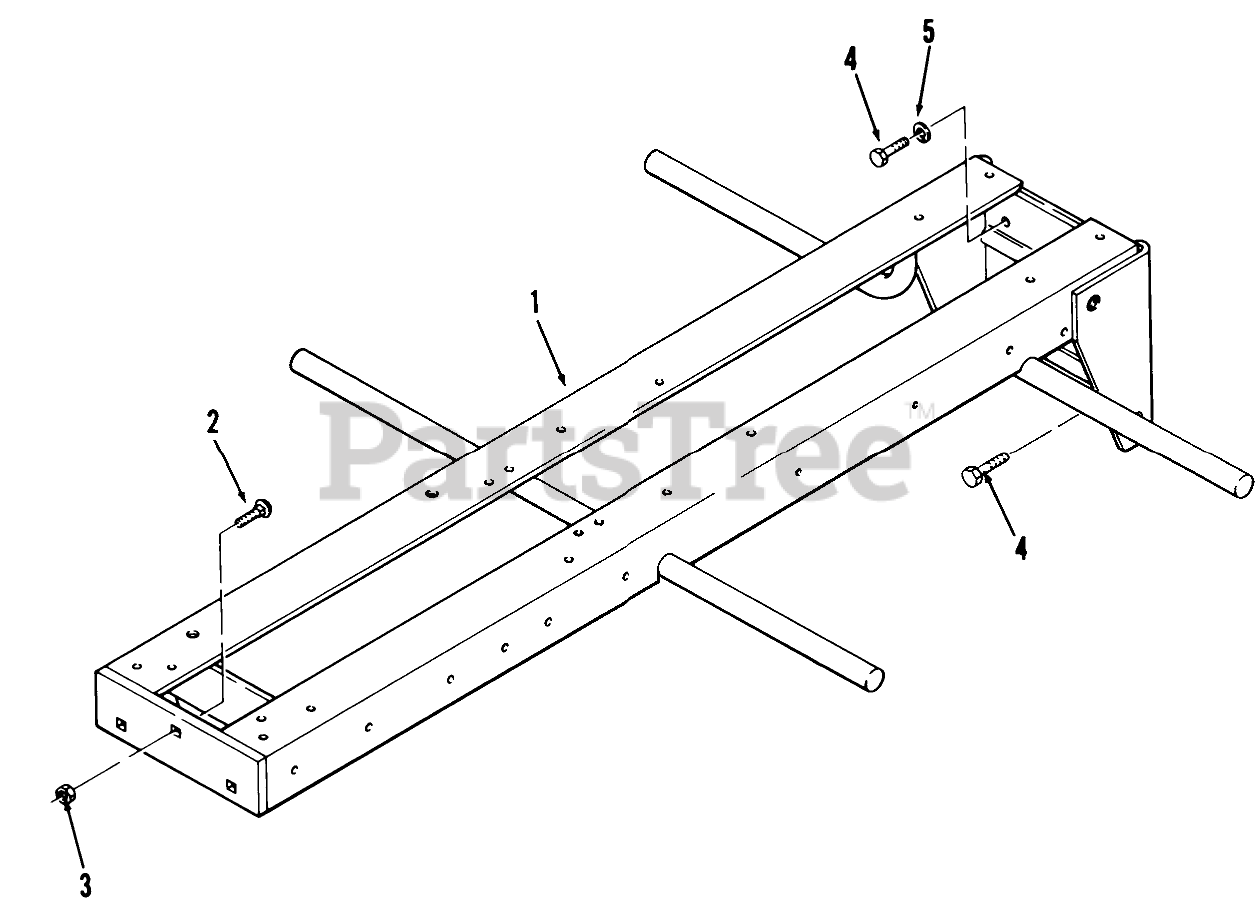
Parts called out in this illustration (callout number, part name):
1	Frame
2	Bolt
3	Nut
4	Bolt
5	LOCKWASHER
